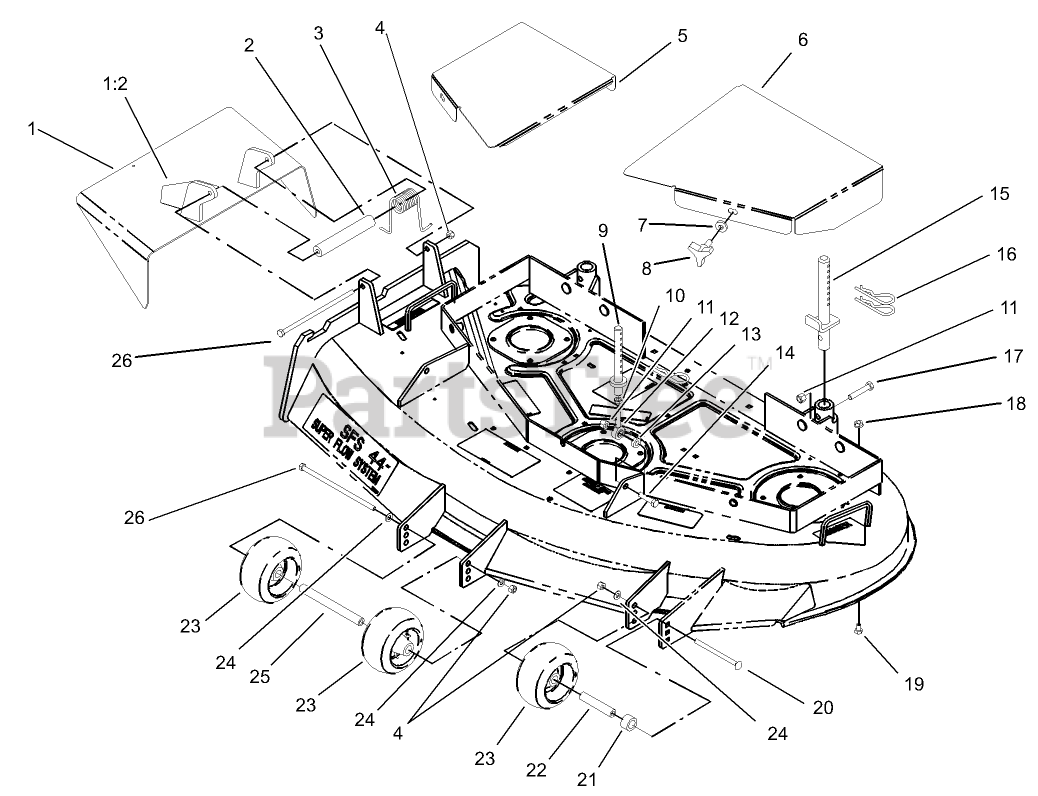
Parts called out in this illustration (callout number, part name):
1	Deflector ASM
1:2	DECAL-DANGER
2	SPACER
3	SPRING-TORSION
4	NUT-LOCK, NI
5	COVER-BELT, RH
6	COVER-BELT, LH
7	WASHER-RUBBER
9	FRONT PIN ASM
10	NUT-HJ
11	NUT-LOCK, NI
12	BALLJOINT
13	SPACER
14	SCREW-HH
15	REAR PIN ASM
16	PIN-HAIR
17	SCREW-HH
18	NUT-HF
19	SCREW-HH
20	SCREW-CARR
21	SPACER-WHEEL
22	BUSHING-ROLLER
23	WHEEL-GAGE
24	WASHER-PLAIN
25	SPACER-WHEEL
26	SCREW-HH
